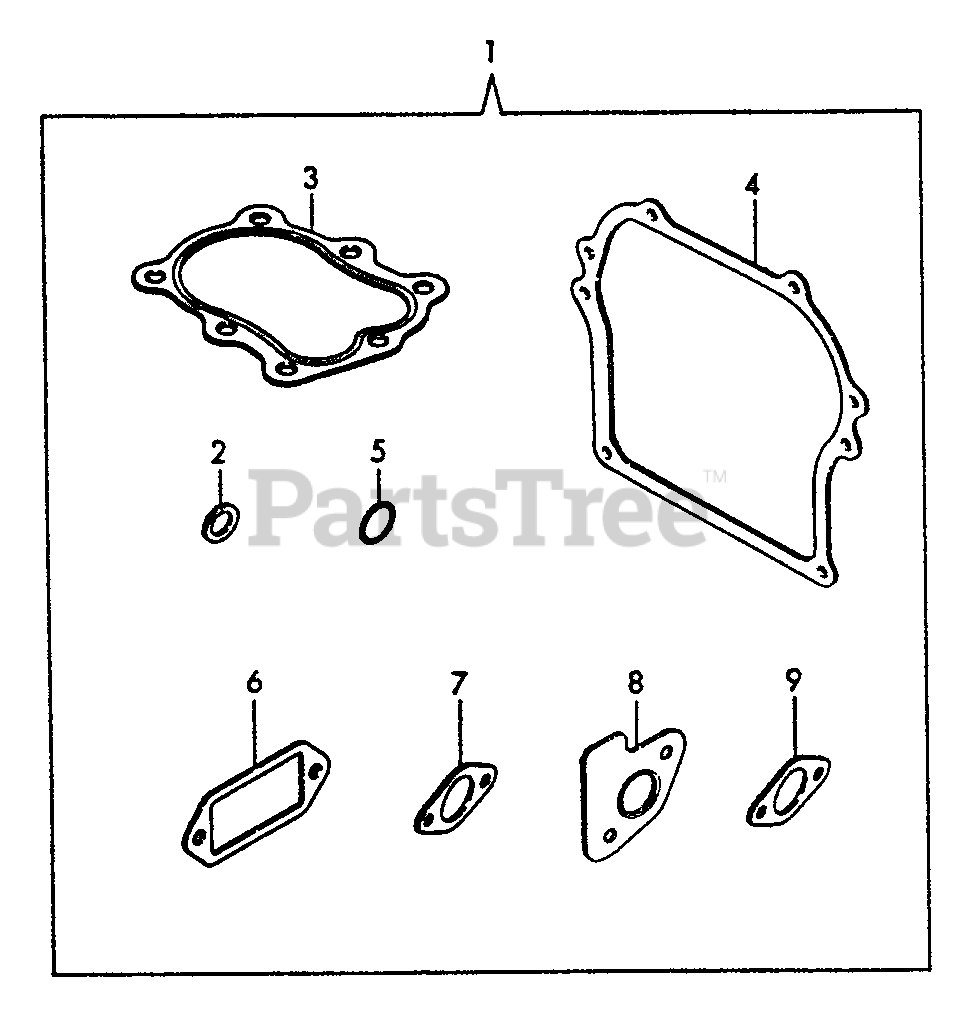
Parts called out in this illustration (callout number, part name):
1	GASKET KIT
2	GASKET
3	GASKET, CYLINDER
4	GASKET
5	O-RING 1A P-18.0
6	GASKET
7	GASKET, INTAKE
8	GASKET, EXHAUST
9	GASKET, EXHAUST
